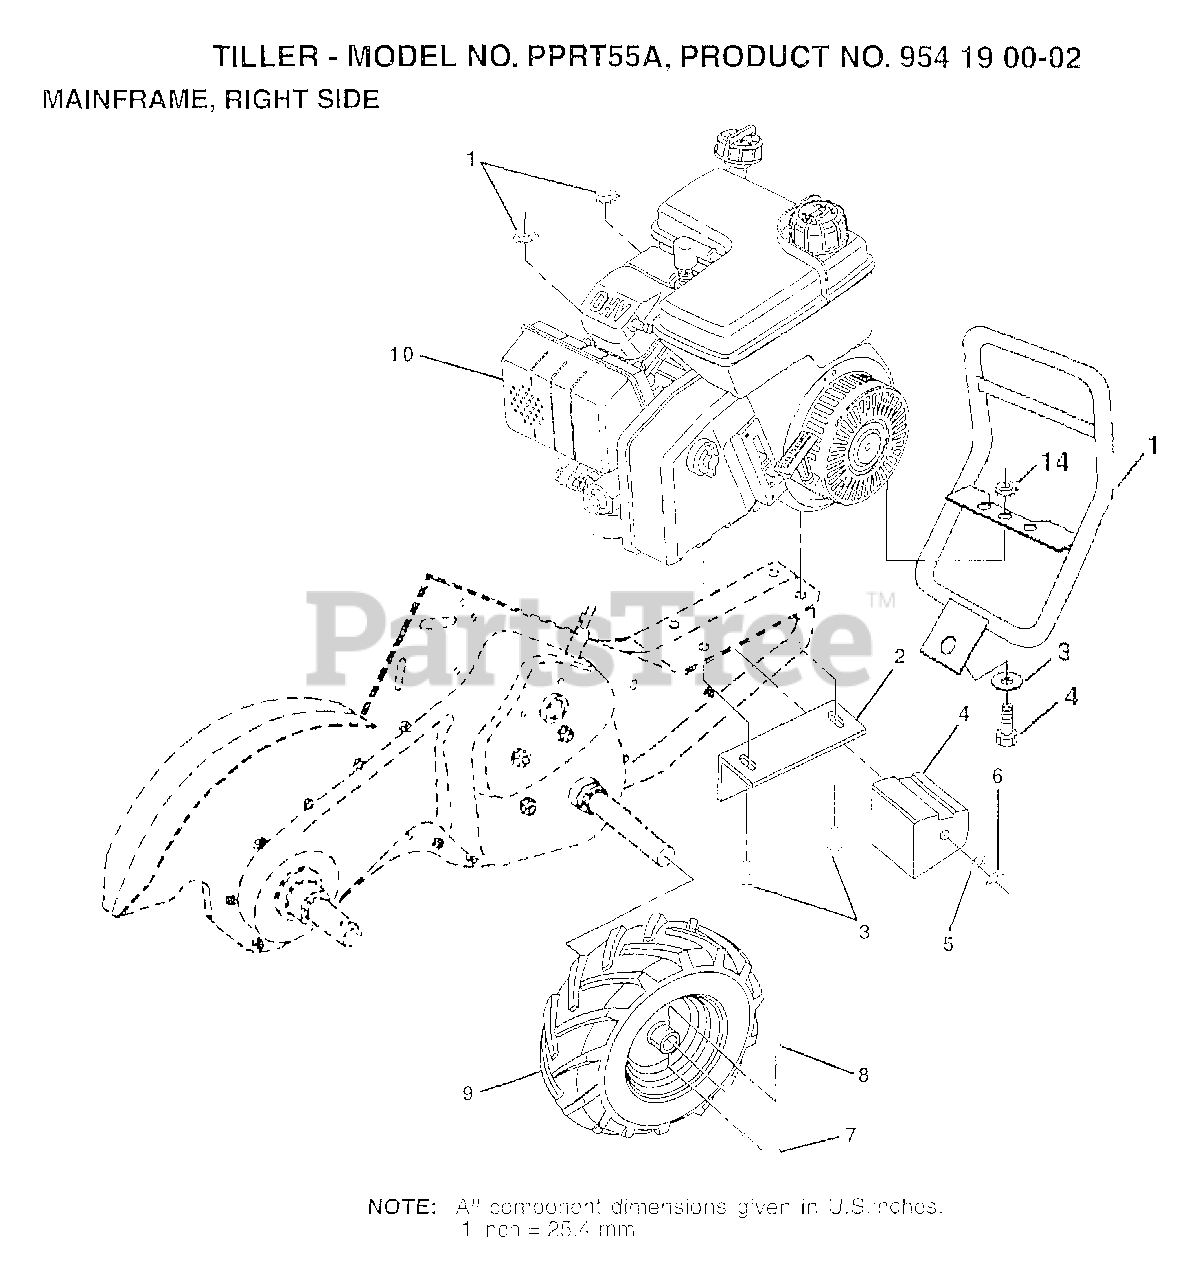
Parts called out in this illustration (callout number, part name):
2	LOCKNUT TI
3	WASHER
4	BOLT
5	BRKT REINFORCEMENT
6	BOLT
7	COUNTER WEIGHT
8	LOCKWASHER
9	NUT.HEX.3/8-16UNC
10	BOLT.HEX.5/16-1.5
12	RIVET DRILLED
13	TIRE TI
